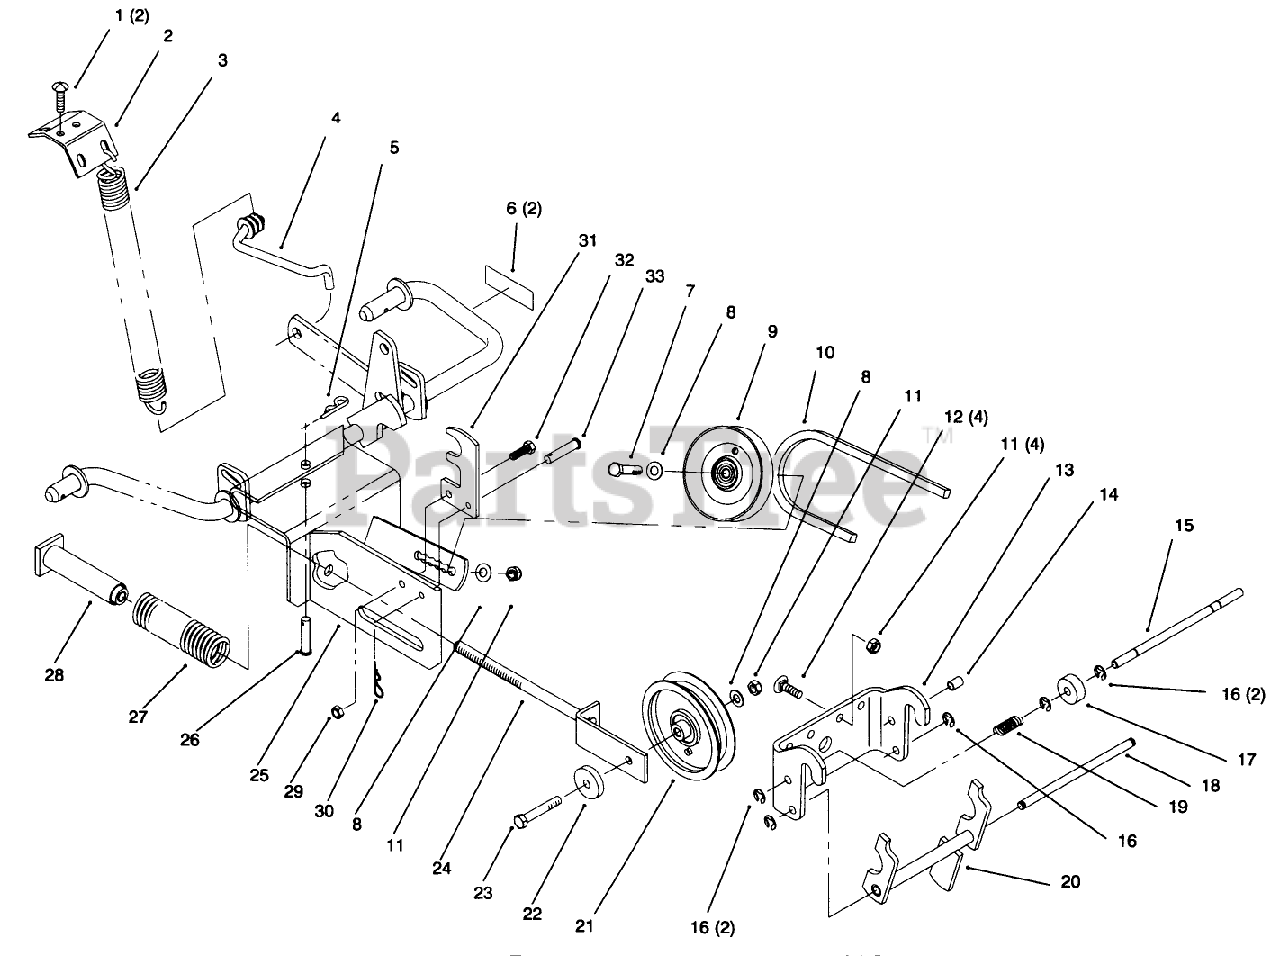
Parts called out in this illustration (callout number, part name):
1	SCREW-CARR
2	BRACKET
3	SPRING-EXTENSION
4	SPRING ROD
5	PIN-HAIR
6	DECAL-WARNING
7	SCREW-HH
8	WASHER-FLAT
9	PULLEY-IDLER
10	V-BELT
11	NUT-LOCK, NI
12	SCREW-CARR
13	HITCH-FRONT
14	CAP-ROD, PLUNGER
15	ROD-LOCK
16	RING-RETAINING
18	ROD-LATCH PIVOT
19	SPRING
20	LATCH
21	PULLEY - FLAT IDLER
22	BUSHING
23	SCREW-HH
24	IDLER SLIDE
25	IDLER SUPPORT
26	Clevis Pin
27	SPRING-COMPRESSION
28	SPRING-TENSIONER
29	NUT-LOCK, NI
30	PIN-HAIR
31	Catch-Idler Support
32	SCREW-HH
33	PIN-CLEVIS
